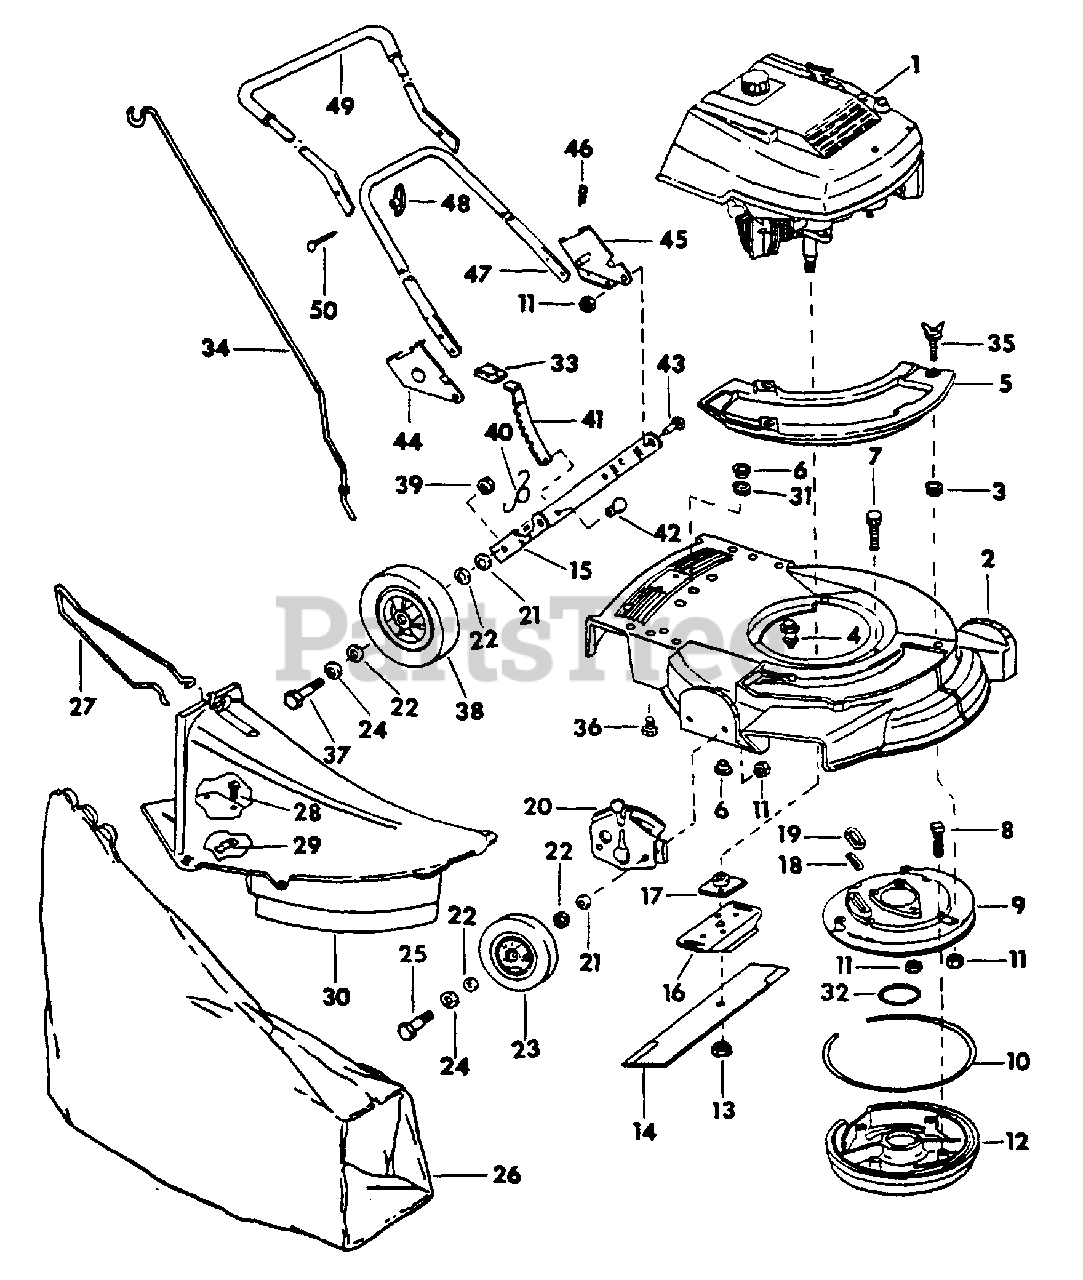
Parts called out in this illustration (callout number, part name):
1	ENGINE, IH
2	HOUSING ASSY, 21 IN.
3	NUT, GROMMET
4	SCREW, SHOULDER
5	COVER, CHUTE OPENING
6	SPACER, FLAGGED
7	SCREW, MUFFLER PLT TO HSG
8	SCREW, MUFFLER TO PLATE
9	PLATE, MUFFLER
10	GASKET, MUFFLER OUTSIDE
12	COVER, MUFFLER
16	STIFFENER, BLADE
17	COLLAR & PLATE
18	GASKET, EXHAUST
19	SLEEVE, EXHAUST GASKET
20	ADJUSTMENT, HEIGHT
22	WASHER, FELT
23	WHEEL AND TIRE 6 IN. FRONT
24	WASHER, WHEEL BOLT HD
25	BOLT, WHEEL FRT SHOULDER
27	GUARD, WHEEL
30	CHUTE ASSY
32	GASKET, MUFFLER INSIDE
34	ROD, GRASS BAG
35	SCREW, WING
36	SCREW, HANDLE BRACKET
37	BOLT, REAR WHEEL
38	WHEEL & TIRE 8 IN, REAR
39	NUT, REAR WHEEL BOLT
40	SPRING, HEIGHT ADJ
41	LEVER, REAR HGT ADJ
42	PIN, HEIGHT ADJ LEVER
44	BRACKET & PIN, RH
45	BRACKET & PIN, LH
47	HANDLE, BOTTOM
49	HANDLE & GRIP, TOP
